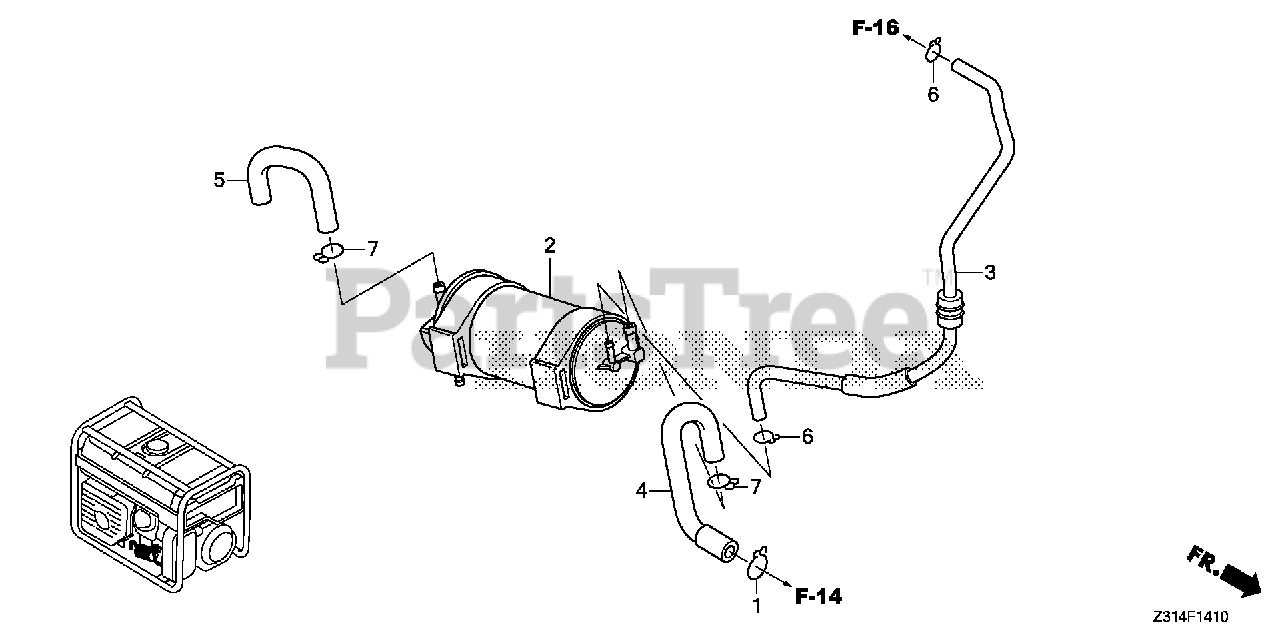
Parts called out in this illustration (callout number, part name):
1	CLIP, BREATHER TUBE
2	CANISTER ASSY.
3	TUBE CANISTER CHARGE
4	TUBE, CANISTER PURGE
5	TUBE, CANISTER AIR
6	CLIP, TUBE (B8)
7	CLIP, TUBE (B12)
